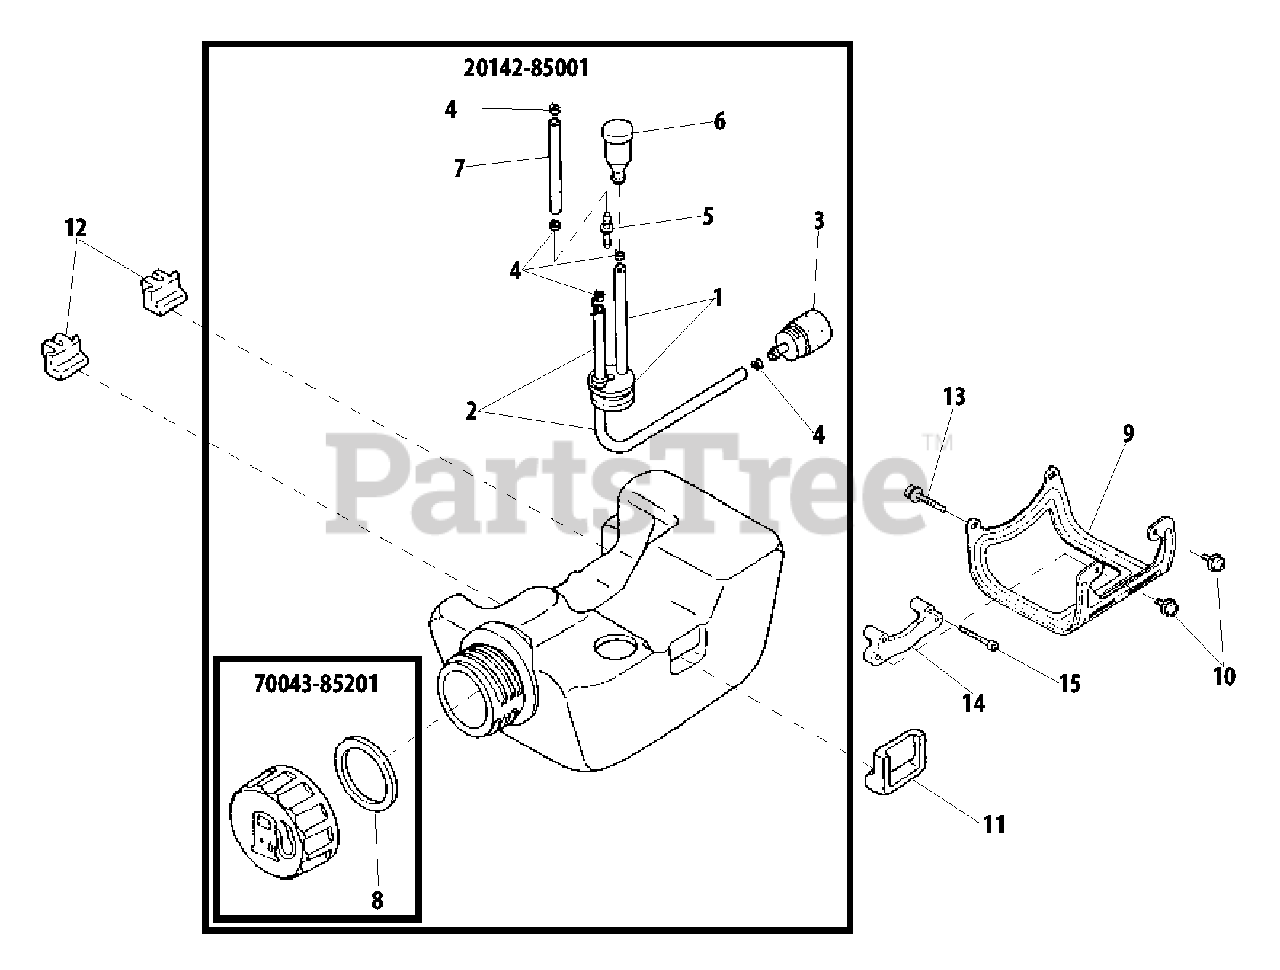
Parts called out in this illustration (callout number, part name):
1	GROMMET
2	PIPE - FUEL
3	FILTER, FUEL
4	RING, RETAINING - 6
5	CONNECTOR, PIPE
6	VENT, FUEL TANK
7	PIPE - RETURN
8	GASKET, CAP
9	GUARD, FUEL TANK
10	SCREW - 5X12
11	CUSHION, TANK
12	CUSHION, TANK
13	SCREW - 5X30
14	BRACKET
15	SCREW - 4X30
20142-85001	FUEL TANK ASSY
70043-85201	CAP ASSY
